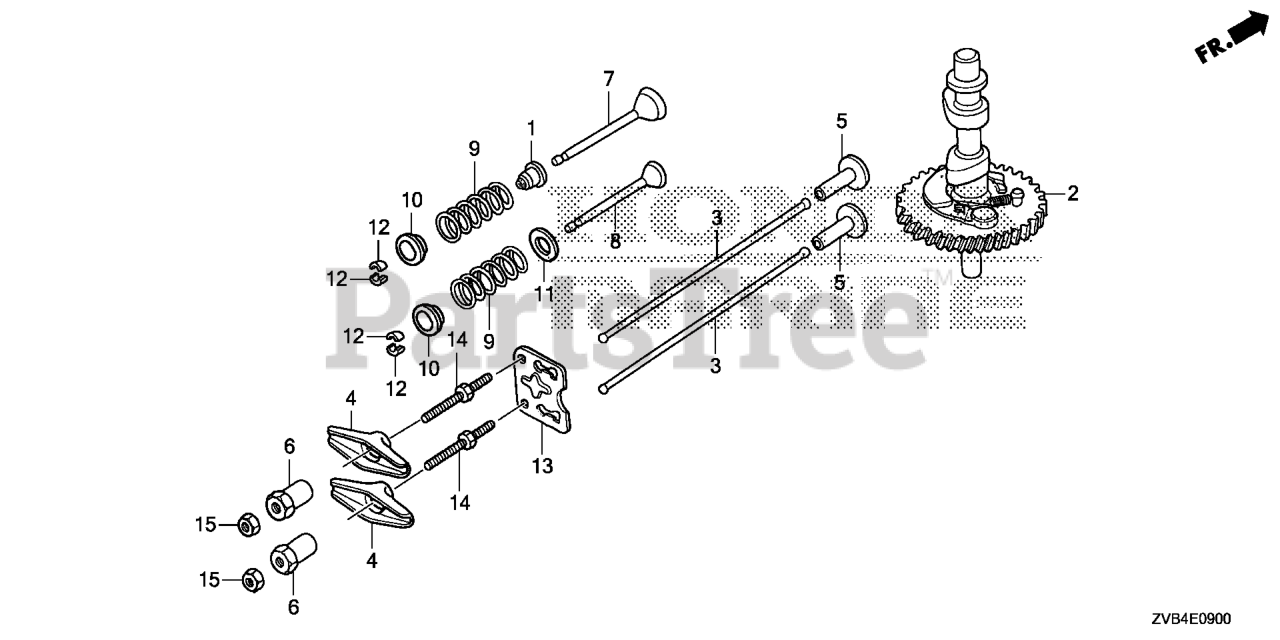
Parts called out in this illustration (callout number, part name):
1	SEAL, VALVE STEM
2	CAMSHAFT ASSY.
3	ROD, PUSH
4	ARM, VALVE ROCKER
5	LIFTER, VALVE
6	PIVOT, ROCKER ARM
7	VALVE, IN.
8	VALVE, EX.
9	SPRING, VALVE
10	RETAINER, VALVE SPRING
11	SEAT, VALVE SPRING
12	COTTER, VALVE (SANKO)
13	PLATE, PUSH ROD GUIDE
14	BOLT, PIVOT (8MM)
15	NUT, PIVOT ADJ.
